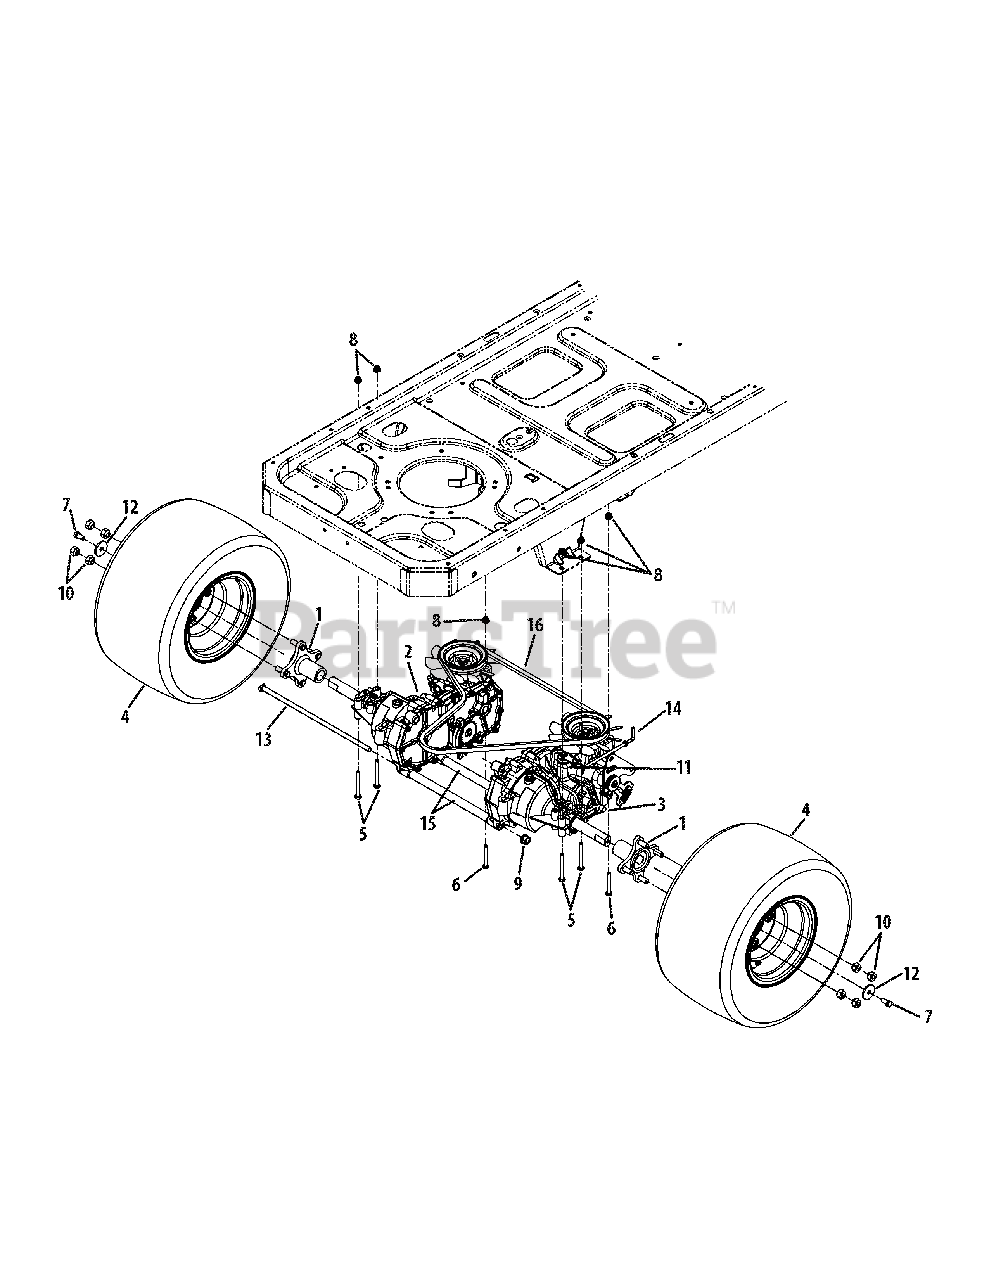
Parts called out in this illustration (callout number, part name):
1	Wheel Hub
2	Transmission Assembly, LH
3	Transmission Assembly, RH
4	Wheel Assembly, 18 x 8.5 x 8
5	Hex Screw, 5/16-18 x 2.75
6	Hex Screw, 5/16-18 x 2.25
7	Hex Lock Screw, 3/8-16 x .75
8	Hex Flange Lock Nut, 5/16-18
9	Hex Flange Lock Nut, 7/16-20
10	Lug Nut, 7/16-14
11	Cotter Pin, 3/32 x .75
12	Flat Washer, .39 x 1.5 x .134
13	Rod, .405 x 14.0
15	Tube, .45 x .69 x 10.2
16	V-Belt
